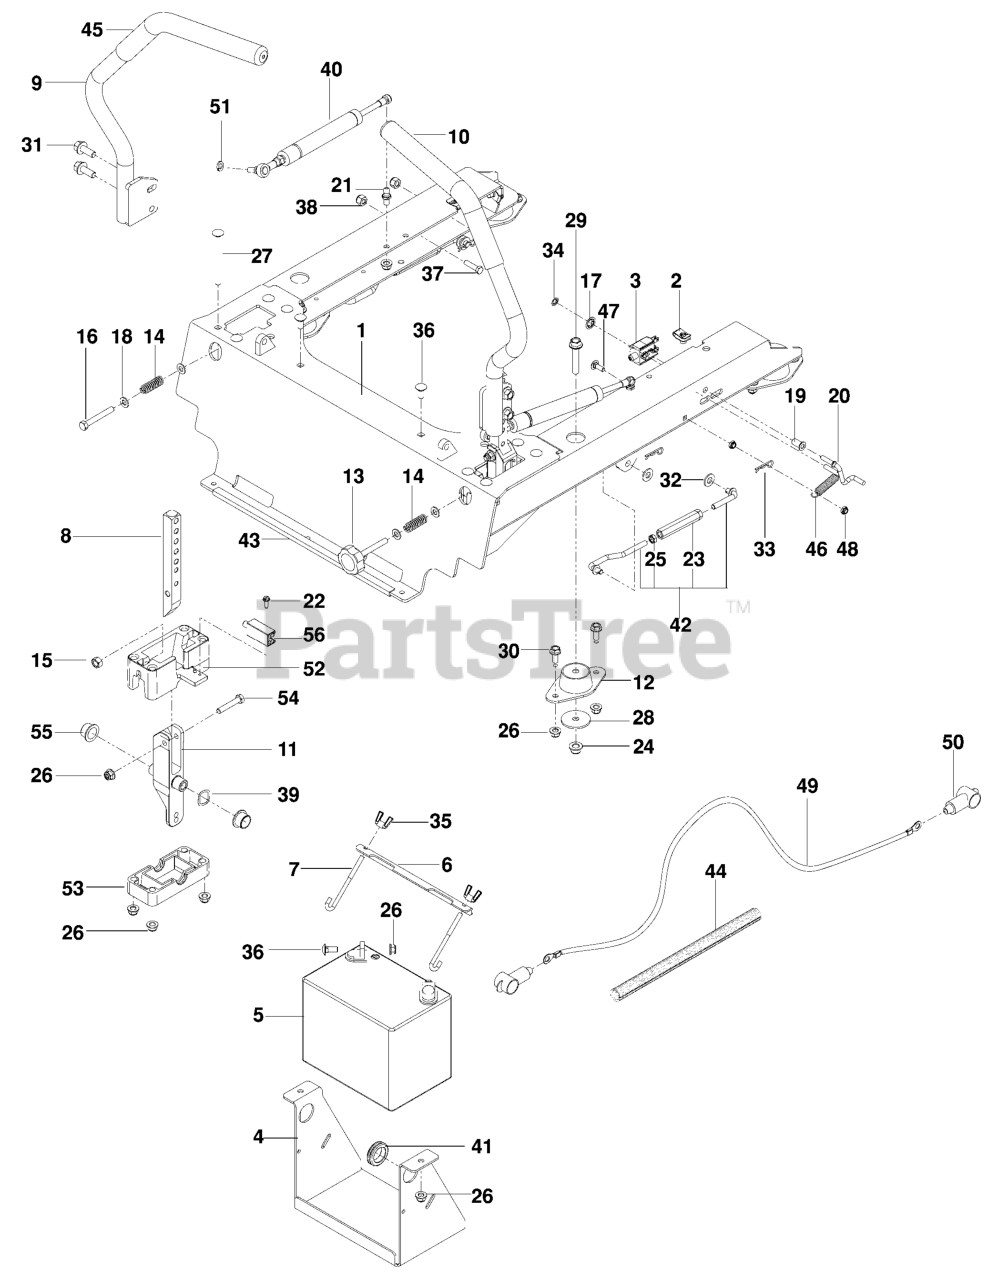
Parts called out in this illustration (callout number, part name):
1	FRAME.SEAT.MOUNT.ORANGE
2	U-CLIP 5/16-18 NUT RETAINER
3	SWITCH, BRAKE 3P
4	BRACKET, BATTERY, BLK
5	BATTERY, 12 V 330 AMP
6	BRACKET, BATTERY MOUNT
7	HOOK, "J"
8	LEVER, MOTION
9	LEVER, W/GRIP, RT
10	LEVER, W/GRIP, LT
11	LEVER, CONTROL
12	MOUNT, ISO
13	KNOB
15	NUT 5/16C HEX
16	HCS 5/16-18 X 2 1/2 TPBLT
17	NUT 3/8 PALNUT RTNG BLK PHOS
18	FLAT WASHER 5/16 SAE
19	BUSHING, 1/4 FLANGE
20	LINK, SWITCH
21	STUD.BALL.10MM
22	SCREW #10 X 1/2 SELF TAPPING
23	TURNBUCKLE, 3/8
24	NUT 3/8-16 HEX FLG NYLOC
25	NUT 3/8-24 JAM
26	5/16-18 NYLOC FLANGE NUT
27	RHSNB 5/16-18 X 3-3/4 GR 5 ZD
28	WASHER, 3/8 SPEC
29	HHFS 3/8-16 X 2.0 GD 5
30	HHFS 5/16-18 X 3/4
31	HHFS 3/8-16 X 1 GRD 5 ZD
32	WASHER 3/8 SAE FLAT
33	HAIRPIN #2
34	NUT PUSH
35	WING NUT 1/4
36	BOLT 5/16C X 3/4" CARRIAGE
37	SCR #10-24 X .75 SKT HD BLK
38	NUT 10-24 NYLOC
39	WASHER, .825 X 1.087, WAVE
40	ASSEMBLY, DAMPENER
41	RUBBER GROMMET
42	ASSEMBLY, SEAT STRUT
43	RP.FLEX TRIM, BLK-LENGTH 1 FT
44	LOOM, SPLIT, CONVOLUTED
45	GRIP - DRIVE LEVER 12"
46	SPRING, EXTENSION
47	RHSNB 1/4C X 3/4
48	JAM NUT 1/4C (2 2 PW01)
49	CABLE, POSITIVE, 55"
51	WASHER.LOCK.HVY.HLCL.SPR.5/16
52	BLOCK, UPPER
53	BLOCK, LOWER
54	HCS 5/16C X 1 3/4
55	BEARING, FLANGE
56	SWITCH, INTERLOCK
